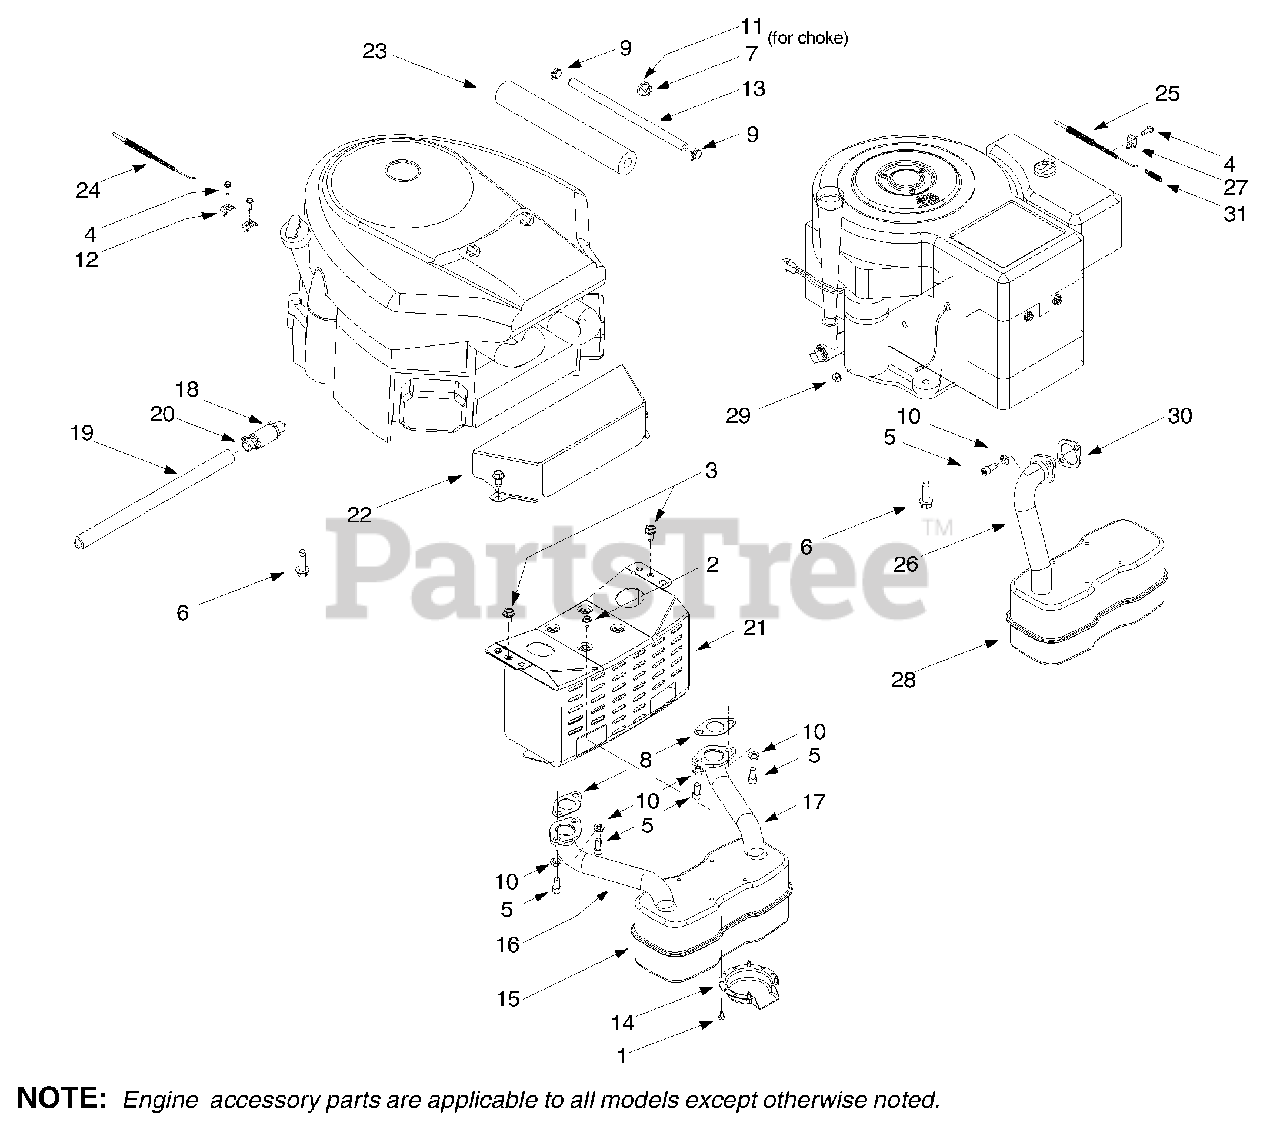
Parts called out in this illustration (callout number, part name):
1	Self-tapping Screw, #8-18 x .5
2	Self-tapping Screw, 1/4-20 x .5
3	Self-tapping Screw, 5/16-18 x .625
4	Screw, #10-32 x .625
5	Socket Cap Screw, 5/16-18 x .625
6	Self-tapping Screw, 3/8-16 x 1.25
7	Hex Nut, 3/8-16 (Model G609G)
8	Exhaust Gasket (Model G609G)
9	Hose Clamp
10	Lock Washer, 5/16
11	Flat Washer (Model G609G)
12	Casing Clamp (Model G609G)
13	Fuel Line Hose
14	Muffler Deflector
15	Muffler, Twin Inlet (Model G609G)
16	RH Exhaust Pipe (Model G609G)
17	LH Exhaust Pipe (Model G609G)
18	Oil Drain Valve
19	Oil Drain Hose
20	Oil Drain Cap
22	Engine Heat Shield (Model G609G)
23	Foam (fits over fuel line)
24	Throttle Cable (Model G609G)
25	Throttle Cable (Model D609G)
26	Exhaust Pipe (Model D609G)
27	Casing Clamp (Model D609G)
28	Muffler, Single Inlet (Model D609G)
29	Hex Sems Nut, 1/4-20 (for starter cable)
30	Exhaust Gasket (Model D609G)
